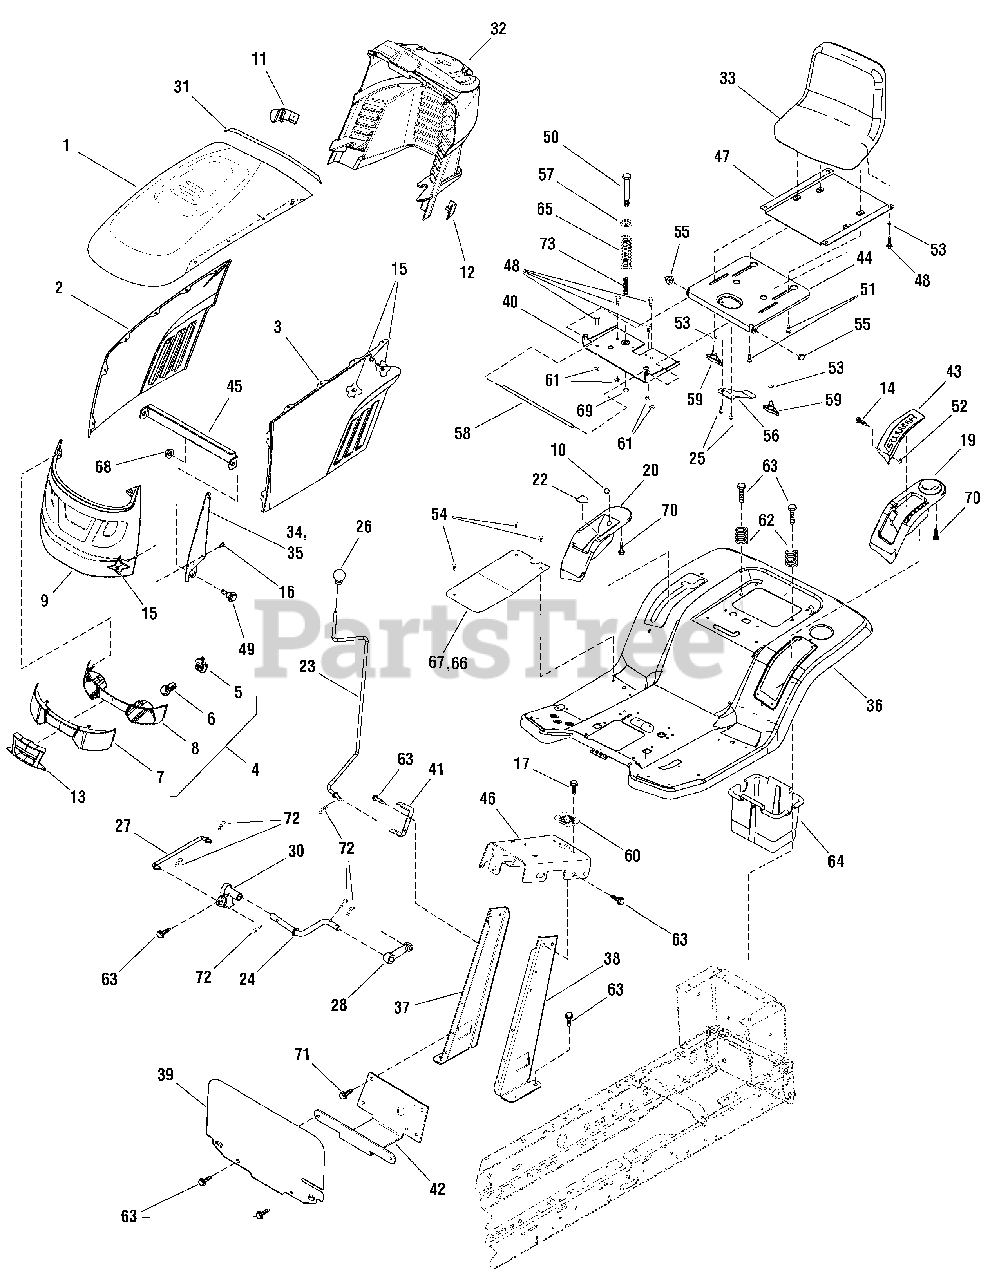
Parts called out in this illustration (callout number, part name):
1	HOOD, 3 Louvers
2	PANEL, Side, Right
3	PANEL, Side, Left
4	HEADLIGHT ASSEMBLY
5	SOCKET
6	BULB, Headlight
7	LENS, Headlight
8	REFLECTOR, Headlight
9	GRILLE
10	PLUG, Hole
11	GUIDE, Hood, Left
12	GUIDE, Hood, Right
13	TRIM, Light Bar, Center
14	SCREW, Hex Washer, Taptit, #10 x 1/2
15	NUT, Hex Flange, 1/4-20
16	SCREW, Hex Flange, 1/4-20 x 5/8
17	SCREW, Self Tap, 1/4-20 x 3/4
19	POD, With Cup Holder
20	POD, With Compartment
22	INDICATOR, Cutting Height
23	ACTUATOR, Cruise
24	ROD, Pivot Cruise
25	SCREW, 1/4-16
26	KNOB, Pull, 1/4-20
27	LINK, Cruise Rod
28	LINK, Cruise
30	LATCH, Cruise
31	STRIP, Trim
32	CONSOLE
33	SEAT, High Back
34	BRACKET, Pivot Hood, Right
35	BRACKET, Pivot Hood, Left
36	DECK, Seat
37	BRACKET, Dash Support, Right
38	BRACKET, Dash Support, Left
39	BULKHEAD
40	BRACKET, Seat Pivot
41	BRACKET, Support, Cruise
42	STIFFENER, Steering
43	INDEX PLATE
44	SUPPORT, Seat
45	BRACKET, Hood Stiffener
46	SUPPOT, Clutch Rod
47	SEAT PLATE
48	BOLT, Hex, 5/16-18 x 5/8
49	BOLT, Shoulder, 3/8-16 x 1/2
50	BOLT, Shoulder, 1/4-20 x 5/16
51	BOLT, Shoulder, 5/16-18 x 3/8
52	NUT, Mclean, #10-24
53	WASHER, Flat
54	FASTENER, Panel
55	CAP, Push-on
56	LEAF SPRING
57	WASHER, Cup
58	ROD, Pivot
59	BOLT, Wing, 5/16-18 x 5/8
60	BEARING, Steering
61	NUT, Nylock, 5/16-18
62	SPRING, Compression
63	CAPSCREW, 5/16-18 x 3/4
64	CONTAINER, Battery
65	SPRING, Compression
66	MAT, Left
67	MAT, Right
68	NUT, Hex Flange, 3/8-16
69	NUT, Hex Flange Lock 1/4-20
70	SCREW, 1/4-20 x 1/2
71	SCREW, 1/4-20 x 3/8
72	HAIRPIN
73	SPRING, Brake Compression
